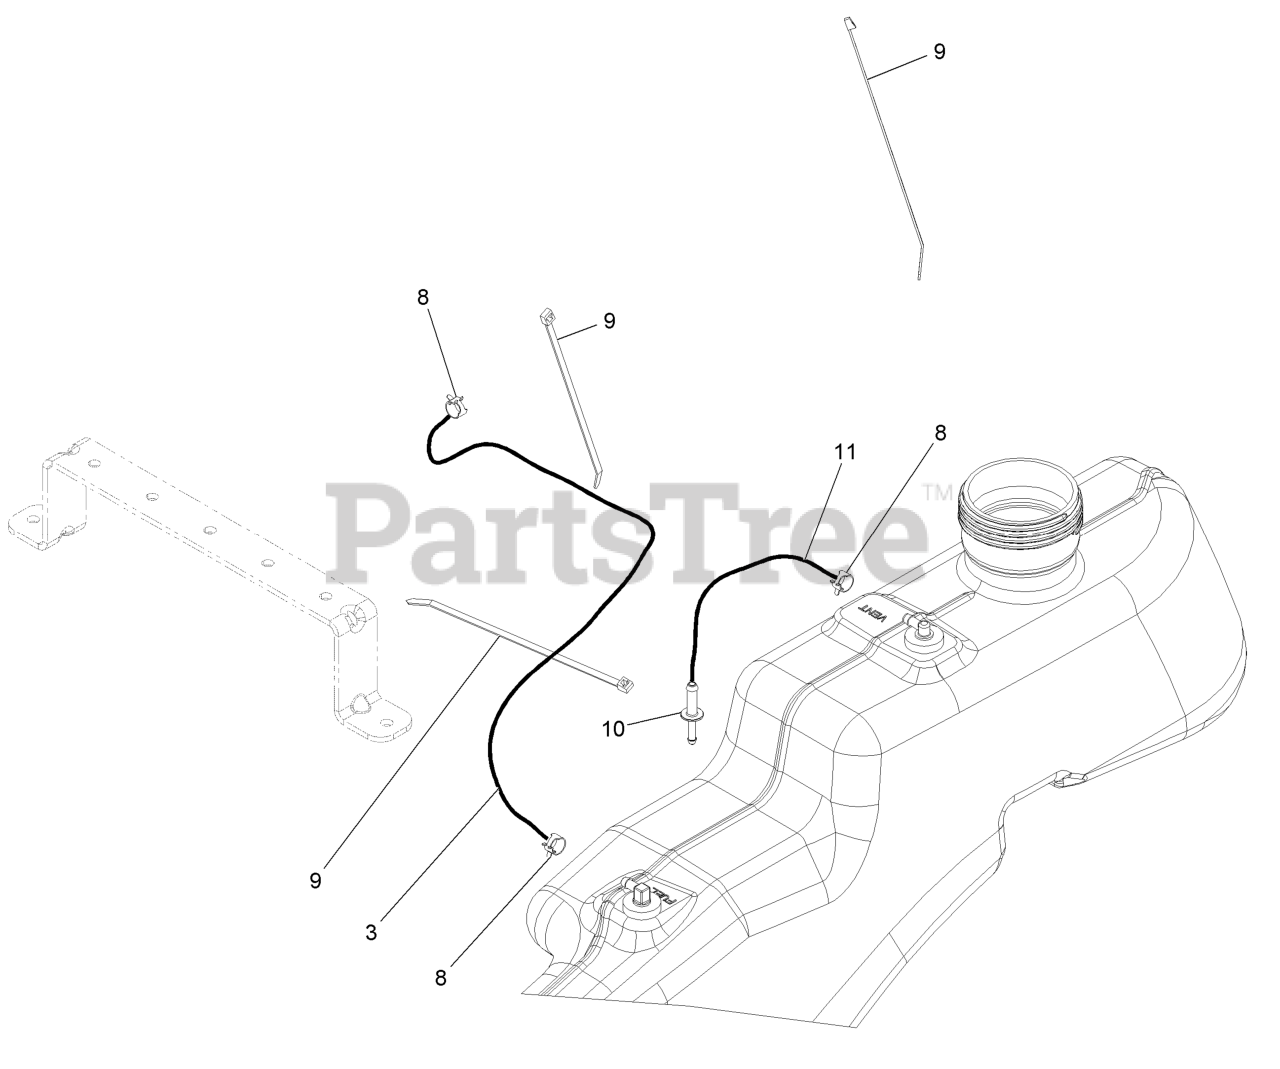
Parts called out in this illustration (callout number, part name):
3	HOSE-FUEL
8	CLAMP-HOSE
9	TIE-CABLE
10	ADAPTOR-ORIFICE
11	HOSE-FUEL
